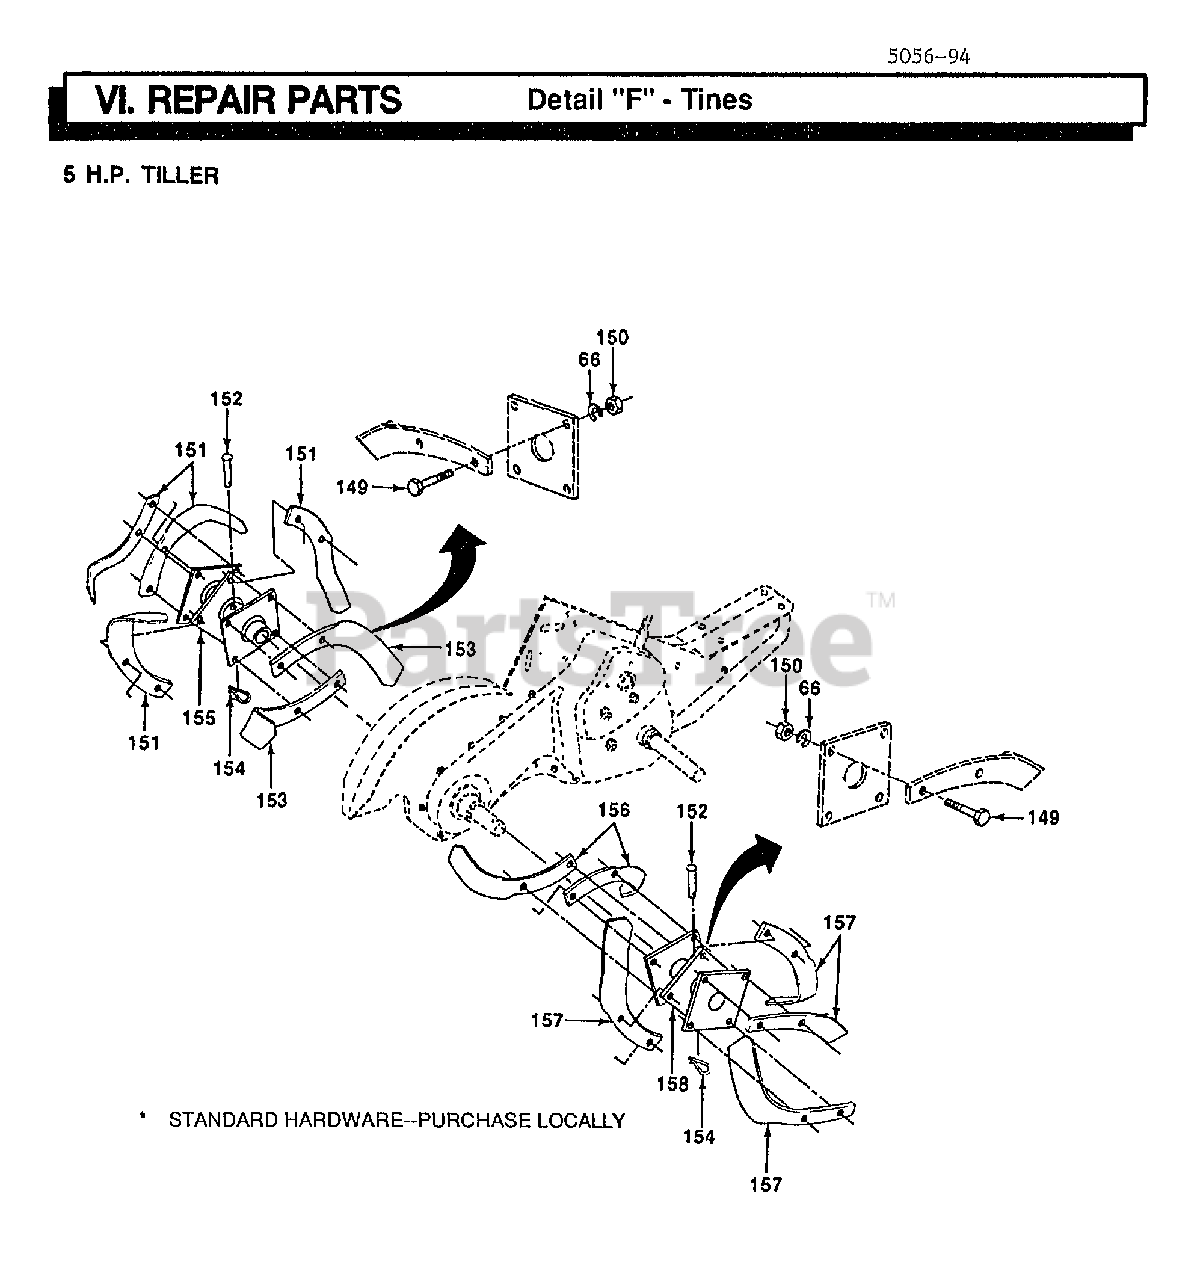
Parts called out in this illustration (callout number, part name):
66	LOCKWASHER
149	BOLT
152	RIVET.PAN HD.1.75
153	"TINE.LH.12"""
154	RETAINER.SPRING
155	TINE ASSY LH CRT
156	"TINE.RH.12"""
158	TINE ASSY RH CRT
